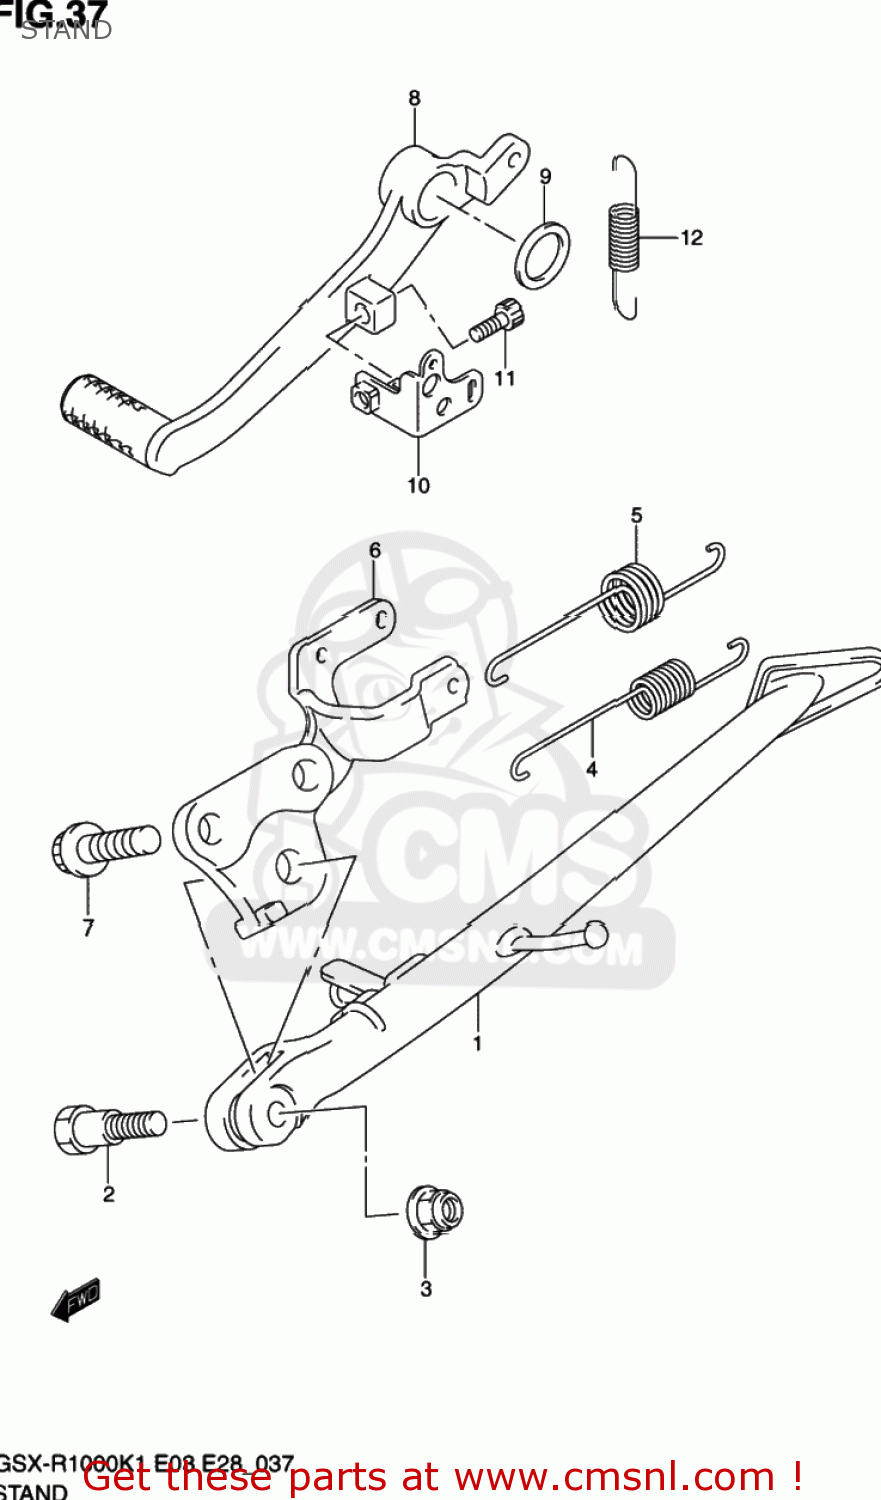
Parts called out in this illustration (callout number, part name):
1	STAND COMP,PRO
2	BOLT(10X21)
3	NUT
4	SPRING
5	SPRING
6	BRACKET COMP,PROP STAND
7	BOLT(10X28)
8	PEDAL,BRAKE
9	WASHER(18X24X1)
10	BRACKET,RETURN SPRING
11	BOLT,OIL FILLE
12	SPRING
